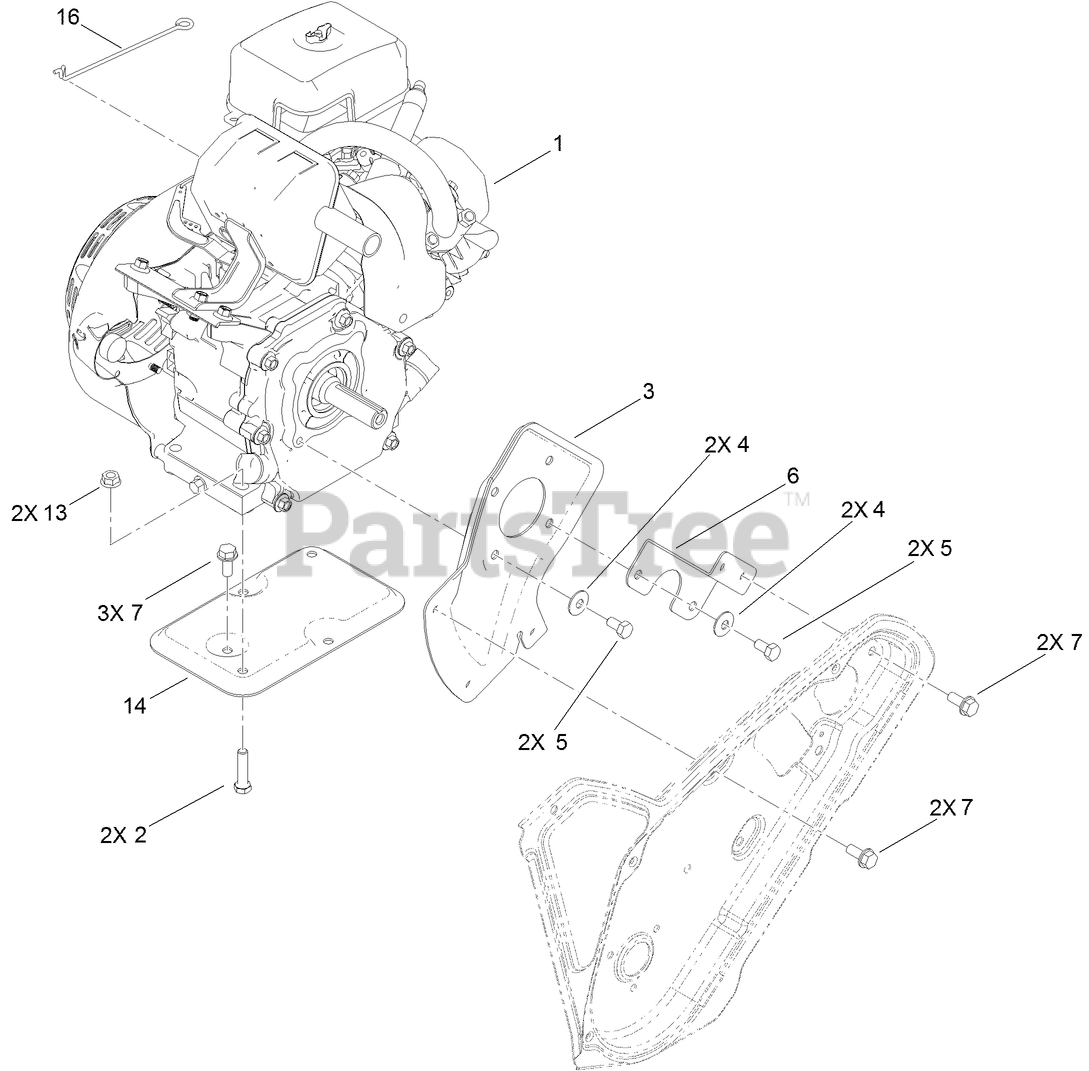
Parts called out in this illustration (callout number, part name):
1	ENGINE-168FS-1
2	SCREW-HH
3	PLATE-ENGINE, PTO
4	WASHER-BELLEVILLE
5	SCREW-HH
6	SUPPORT-ENGINE, SIDE
7	SCREW-THD ROLL, HWH
13	NUT-HF
14	SUPPORT-ENGINE
